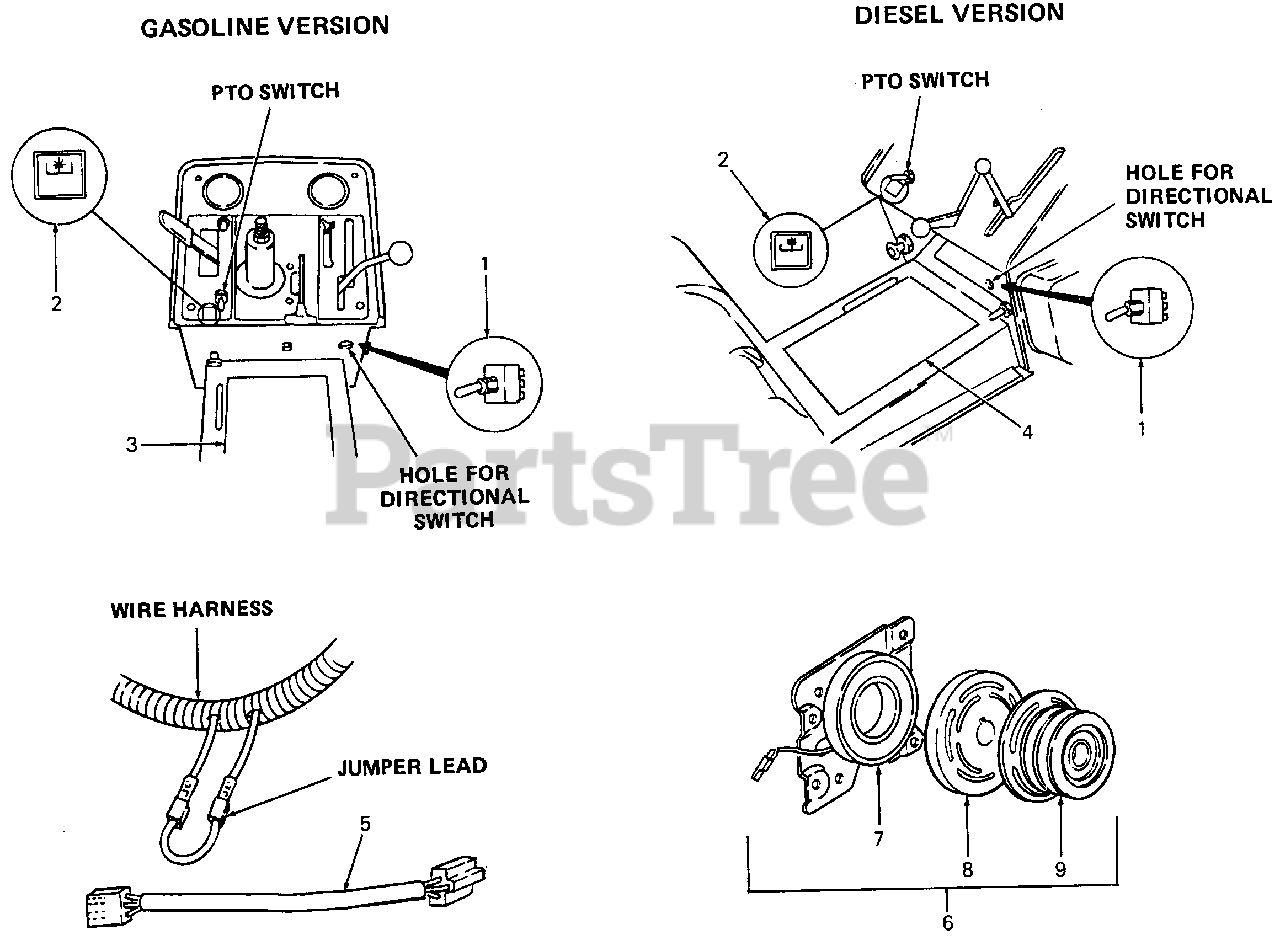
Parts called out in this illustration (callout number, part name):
1	Switch, Directional
2	Plaque, PTO Logo
3	Graphic, Caution (Gas Only)
4	Graphic, Caution
5	Harness Adapter, Directional Switch
6	PTO Clutch
7	Field Assy
9	Armature Assy
